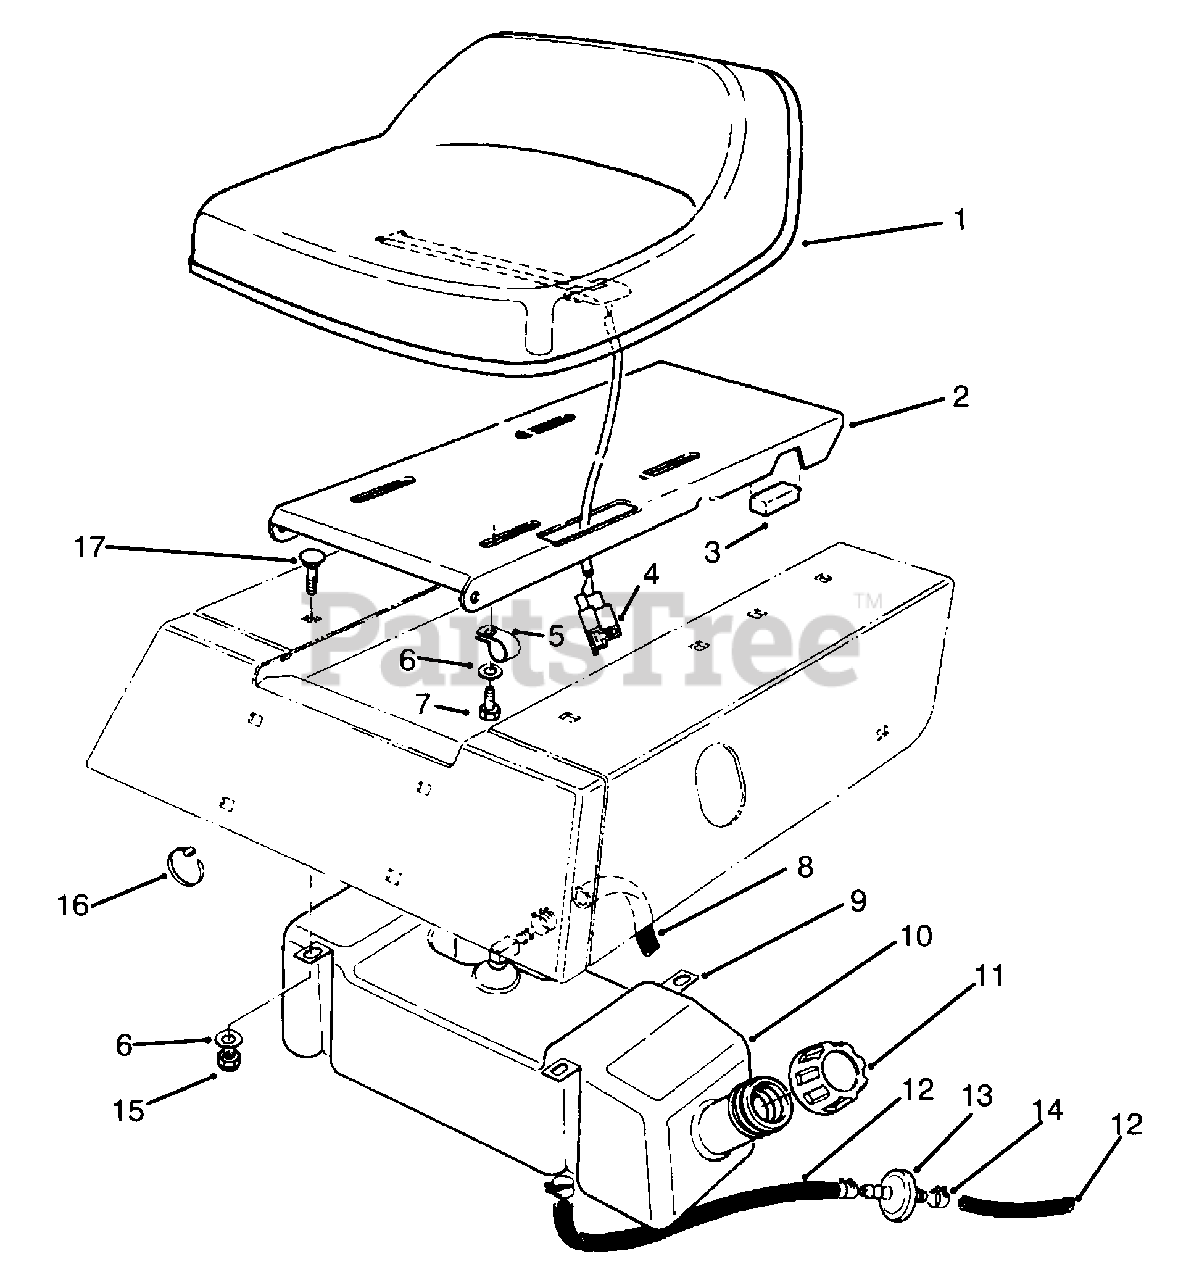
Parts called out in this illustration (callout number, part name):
3	Pad-Isolator
4	Switch-Seat
6	Washer-Flat
7	Screw-Cap Hex. Hd.
8	Hose-Gas
9	Strap-Tank, Gas
10	Tank-Gas
11	Assembly-Cap, Gas
12	Hose-Gas
14	Clamp-Hose
15	Nut-Lock
16	Tie-Cable
17	Bolt-Carriage
